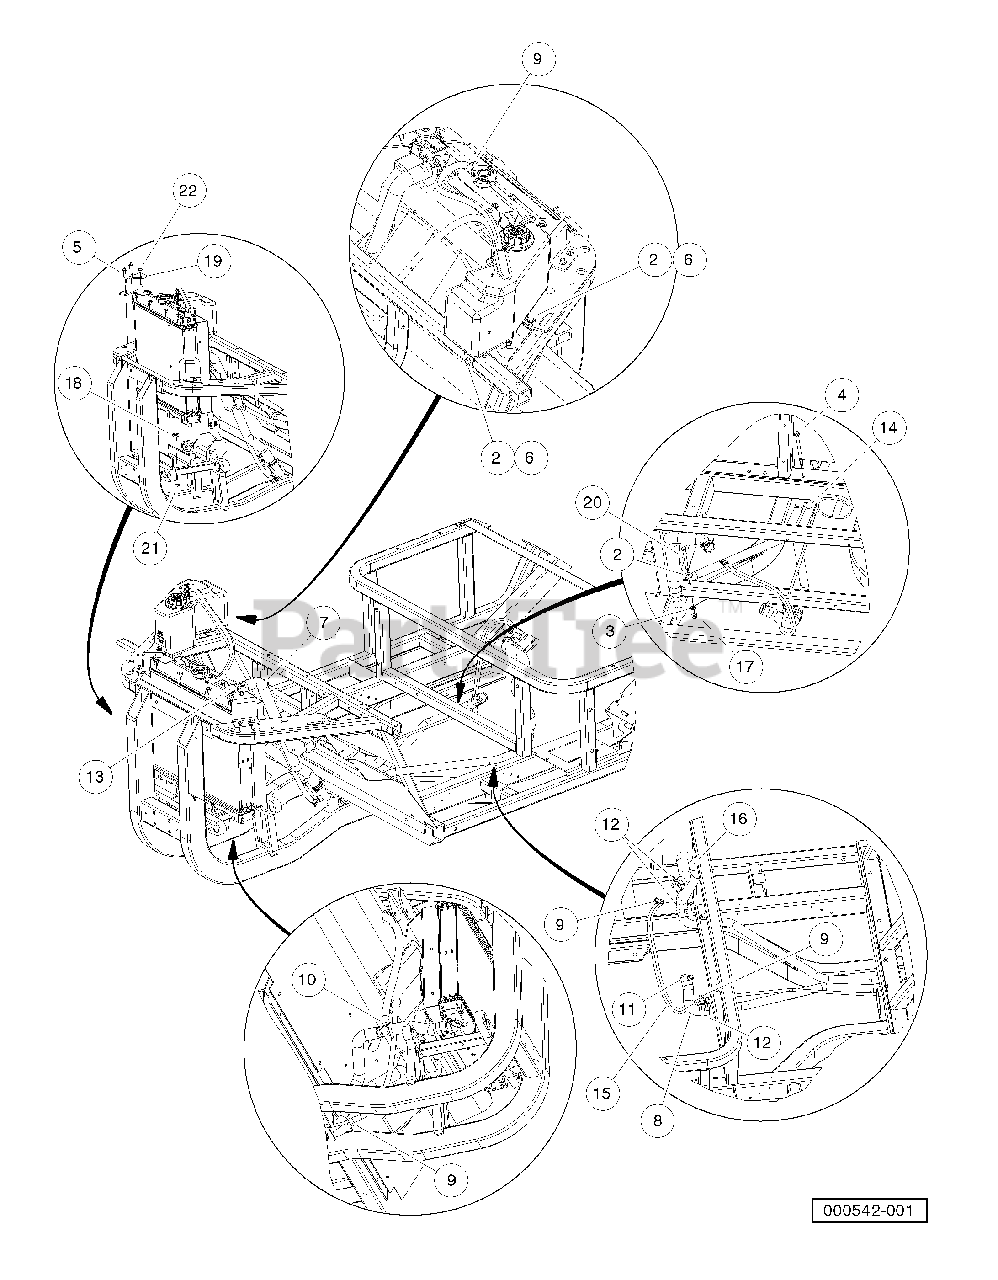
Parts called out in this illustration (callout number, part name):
1	Instl, Cooling Sys, Diesel
2	Washer, 5/16 Type B Flat
3	Spacer, 0.720"
4	Bolt-hex Fl, M8 X 1.25 X 135
5	Screw, M8X1.25X30, Hex
6	M8-1.25x20 Taptite
7	Hose, Coolant Upper Rad
8	Hose, Coolant Lower Eng
9	Clamp, Hose, CTB 15mm
10	Clamp, Hose, CTB 22mm
11	Clamp, Hose, Ctb 30mm
12	Clamp, Hose, Ctb 35mm
13	Clamp, Hose, Ctb 38mm
14	Clamp, Bar
15	Hose, Vent Tube To Eng, Coolnt
16	Hose, Coolant, Return, Engine
17	Lock Nut, Flg M8 X 1.25 Nylon
18	Bumper, 19mm Stud
19	Bracket, Radiator Support
20	Bolt, M8 X 1.25 X 110
21	Nut Flg, M6 X 1 Serrated
22	Nut Flg, M8 X 1.25 Serrated
